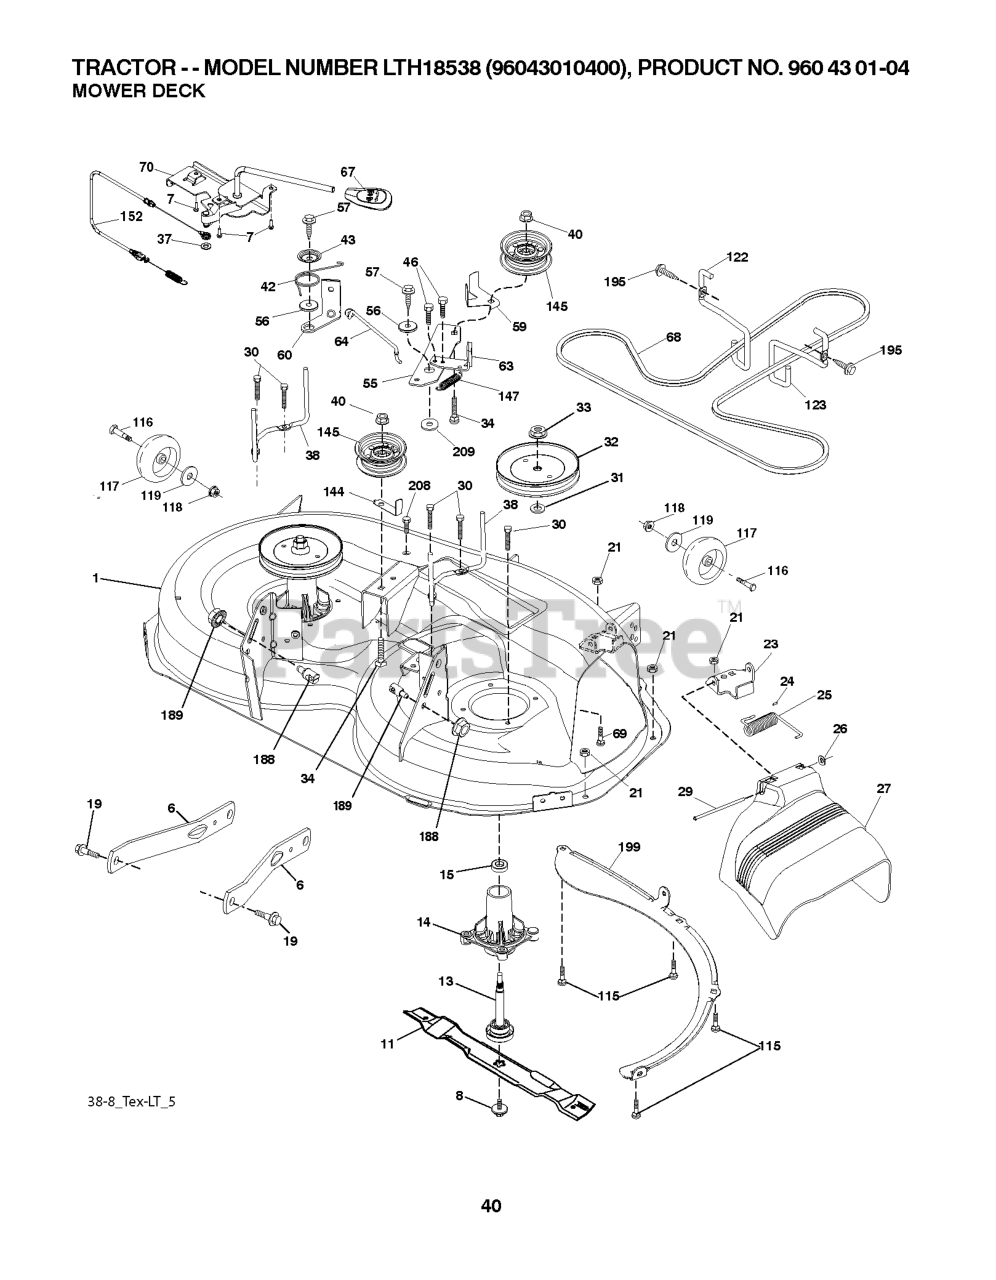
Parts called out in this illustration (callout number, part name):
1	MOWER HOUSING
6	ARM.SUSPENSION.MOWER.R
7	SCREW.#10 X 0.750.BOS
8	BOLT.WASHER.ASM.7/16-2
11	BLADE.HI.LIFT.38"
11	BLADE 38" PREMIUM
13	SHAFT.ASM.MDRL.N/GREASE.38
14	RP.HOUSING.MANDREL.4PT.
19	BOLT.SHOULDER
21	LOCKNUT
23	BRKT.DEFLECTOR.38"2005+
24	CAP-SLEEVE LT
25	SPRING.TORSION.DEFLECT
26	NUT PUSH M
27	SHIELD, DEFLECTOR
29	ROD.HINGE
30	SCREW, WASHER HEAD
31	WASHER.SPACER.MANDREL
32	PULLEY.MANDREL.5.0.PD.38"
33	NUT.FLANGE.LOCK.TOP
34	BOLT.3/8-16X1.50
37	WASHER
38	KEEPER BELT LH MANDREL
40	NUT LOCK FLG 3/8-16 UNC
42	SPRING.TORSION.BRAKE
43	SRPING.TORSION.RETAINE
46	SCREW.1/4-20X5/8
56	SPACER.RETAINER
57	SCREW 3/8-16X1
59	GUARD, BELT
60	ARM BRAKE MOWER RH 38"
63	RP ARM.BRAKE.MOWER.38"LH.TEX
64	LINKAGE.BRAKE.ASM.ZINC
67	HANDLE.CLUTCH.CABLE.LT
69	BOLT
70	CLUTCH.ASM.MANUAL.LT.PRED
115	BOLT.CARR.5/16-18X5/8.SHORT
116	BOLT M
117	WHEEL.GAGE.HALF.SPOKED
118	LOCKNUT
119	WASHER.5/16.FLAT.STE.STD.
122	KEEPER BELT ENGINE LH
123	KEEPER BELT RH
144	KEEPER BELT
145	PULLEY.IDLER.48"PRIMARY
147	SPRING RETURN
152	CABLE.CLUTCH.MANUAL.
188	STUD.FASTNER.W/ANTI-ROTATE
189	NUT LOCK HEX FLANGE 5/16-18
195	SCREW, 3/8-16X3/4
199	BAFFLE.VORTEX.FRONT.38"
208	SCREW 3/8-16X1/2
209	WASHER 12/32X2X10GA
